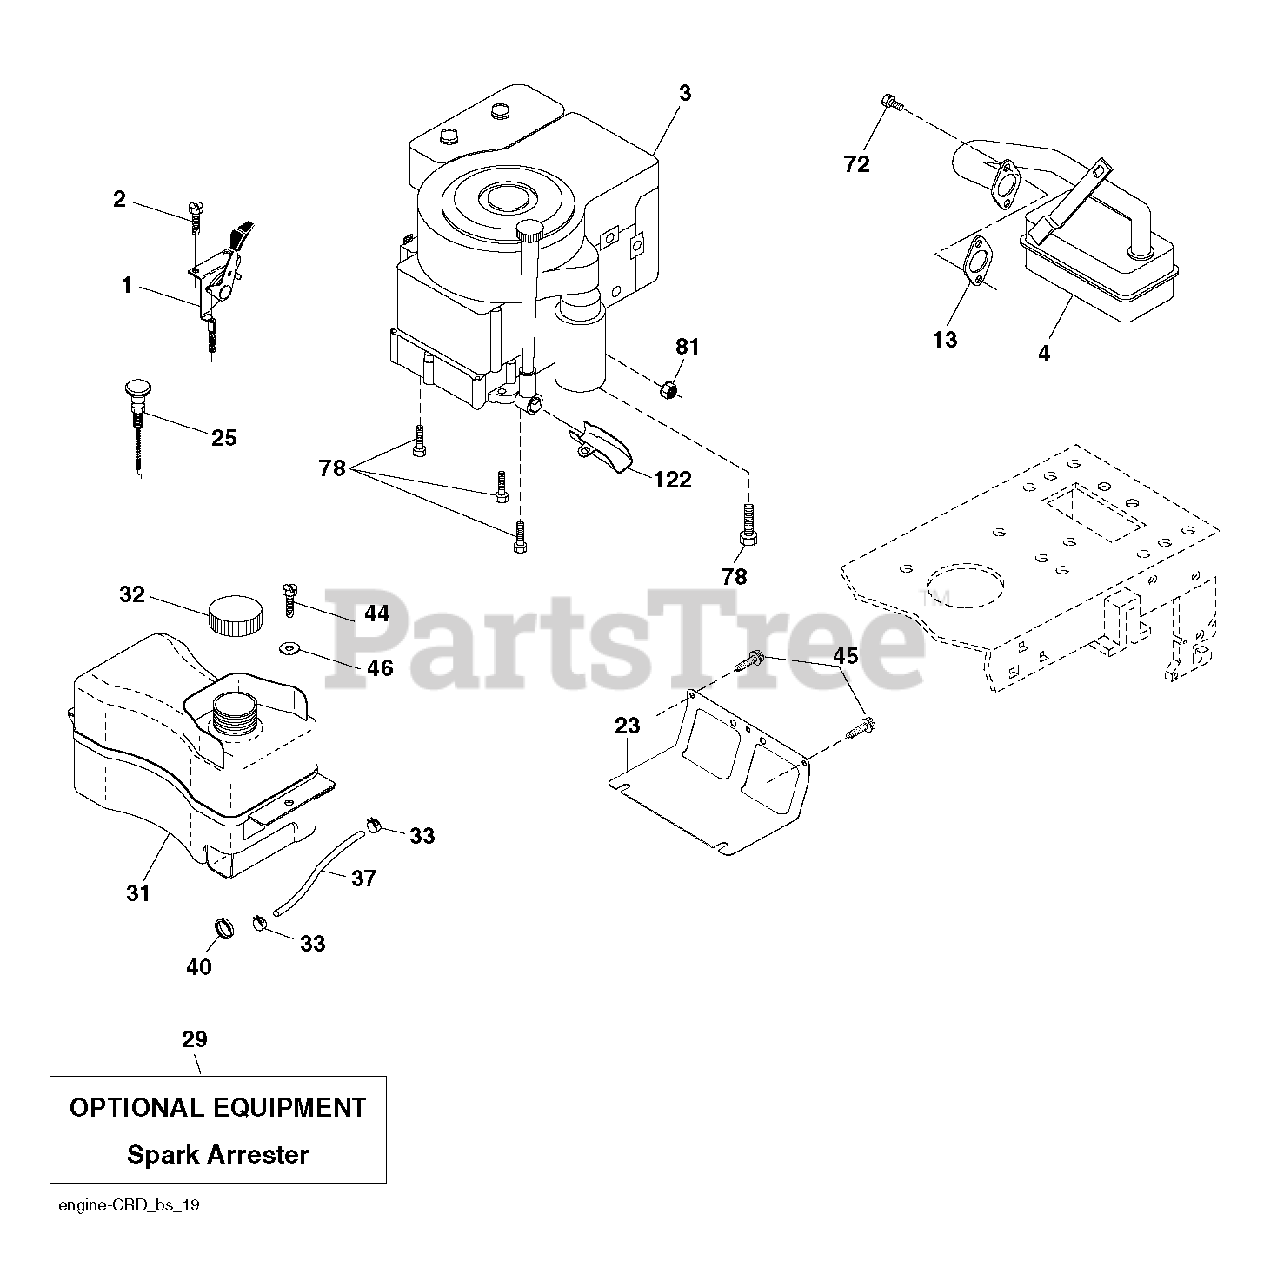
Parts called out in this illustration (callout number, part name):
1	CONTROL TH/CH FLAG
2	SCREW
13	REPL BY 532 27 22-93
23	SHEILD.BROWNING.DBR.GUARD
25	KNOB.ERGO.EXTENDED.RED (1 2)
29	ARRESTER SPARK (OPTIONAL)
32	CAP ASM.FUEL.2.25"FR.
37	LINE.FUEL.20
44	SCREW HEXWSHR 1/4-20X3/4
45	SCREW, 3/8-16X3/4
46	WASHER
72	SCREW.SOCKET HD.5/16-1
81	NUT
122	EXTENSION DRAIN OIL
